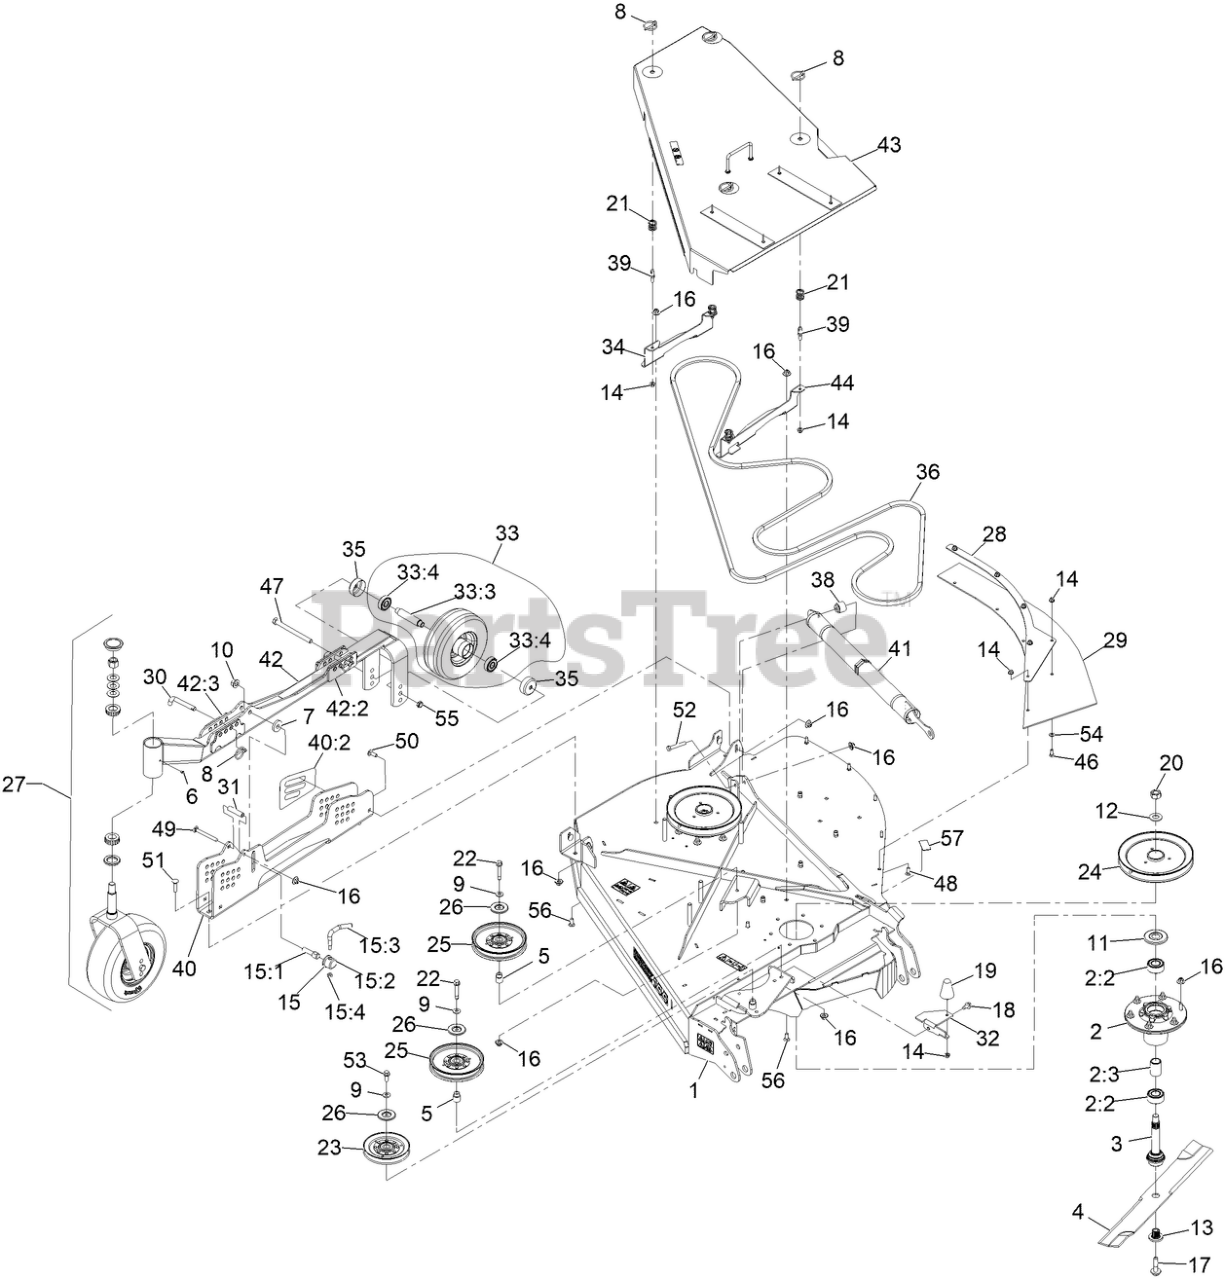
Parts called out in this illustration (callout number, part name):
1	ASM-RH WING DECK 144
2	ASM-CUTTER HSG
2:2	BEARING-3205 TRASHGUARD
2:3	SPACER-BEARING
3	ASM-SPINDLE AND SEAL
5	BUSHING-IDLER
8	PIN-LYNCH
9	WASHER-BELLEVILLE
10	Nut-Lock 1/2-13
11	GUARD-BEARING, TOP
13	BUSHING,SPLINED
14	NUT-HF, NI
15	LEVER ASM
15:1	SCREW-LOCK
15:2	CAP-LOCK
15:4	NUT-LOCK, NI
16	Nut-Nyloc 3/8-16 Flg
17	SCREW,SEMS 1/2-20 X 2.19
18	SCREW-HWH
19	BUMPER-RUBBER
20	NUT-HEX
22	SCREW-HHF
23	IDLER-V
24	SHEAVE-SINGLE 96RD
25	IDLER-PULLEY
26	SHIELD-DUST
27	ASM-CASTER,11"TIRE
28	SUPPORT-RH REAR GUARD
29	GUARD-RH REAR WING
30	PIN-HOC
32	BRACKET-COVER RETAINER
33	WHEEL AND TIRE ASM
33:3	AXLE-CASTER
33:4	BEARING
34	BRACKET-SHIELD MOUNT, OUT
35	GUARD, SEAL
38	BUSHING-LIFT SPRING
39	PIN, SPRING
40	ASM-CHANNEL, HOC RH W/DECALS
40:2	DECAL-HEIGHT OF CUT, RH
41	ASM-WEIGHT-TRANSFER-SPRING
42	ASM-RH GAUGE WHEEL ARM
42:2	PLATE-GUIDE, REAR
42:3	PLATE-GUIDE, FRONT
43	ASM-BELT SHIELD RH
44	BRACKET-SHIELD MOUNT, RIGHT LONG
46	SCREW-HH
47	SCREW-HH
48	SCREW-CARR
49	SCREW-CARR
50	BOLT-CARR
51	SCREW-CARR
52	SCREW-HH
53	SCREW-HHF 3/8-16 X 1
54	WASHER-PLAIN
55	NUT-HEX
56	BOLT-CARR
57	PAD-RUBBER
